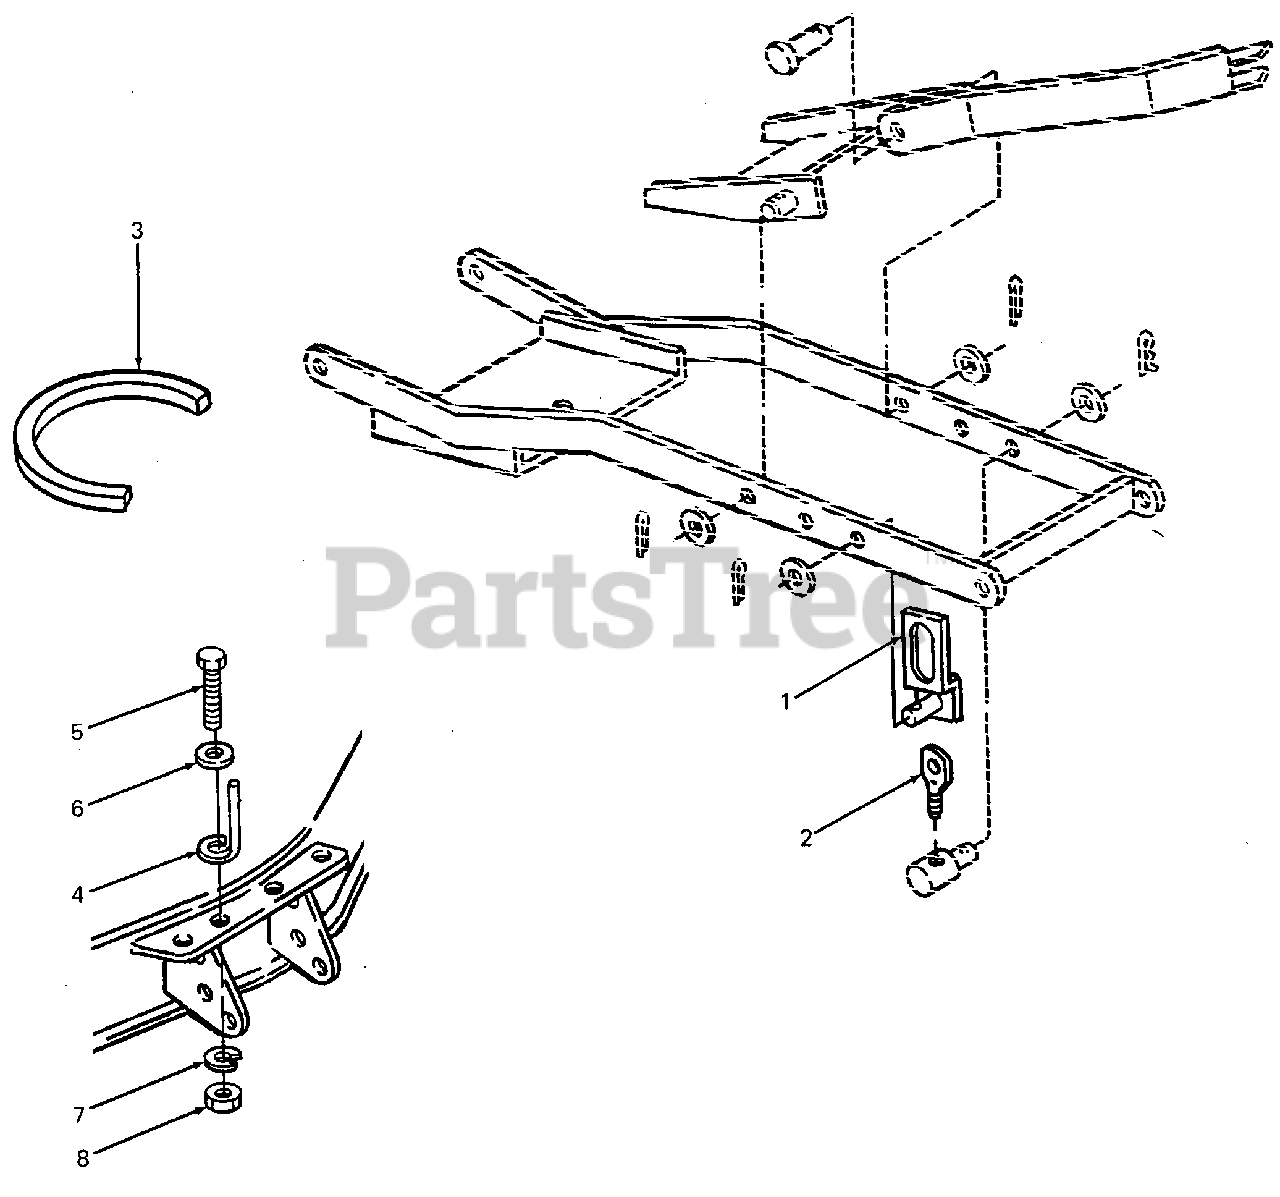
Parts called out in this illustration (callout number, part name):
3	Belt, Mule Drive
4	Rod, Belt Guide
5	Screw, Hex Cap, 3/8-16 X 1.0 Long GR5
6	Washer, Flat, .406 X .75 X .06
7	Washer, Lock, 3/8
8	Nut, Hex, 3/8-16 GR5
